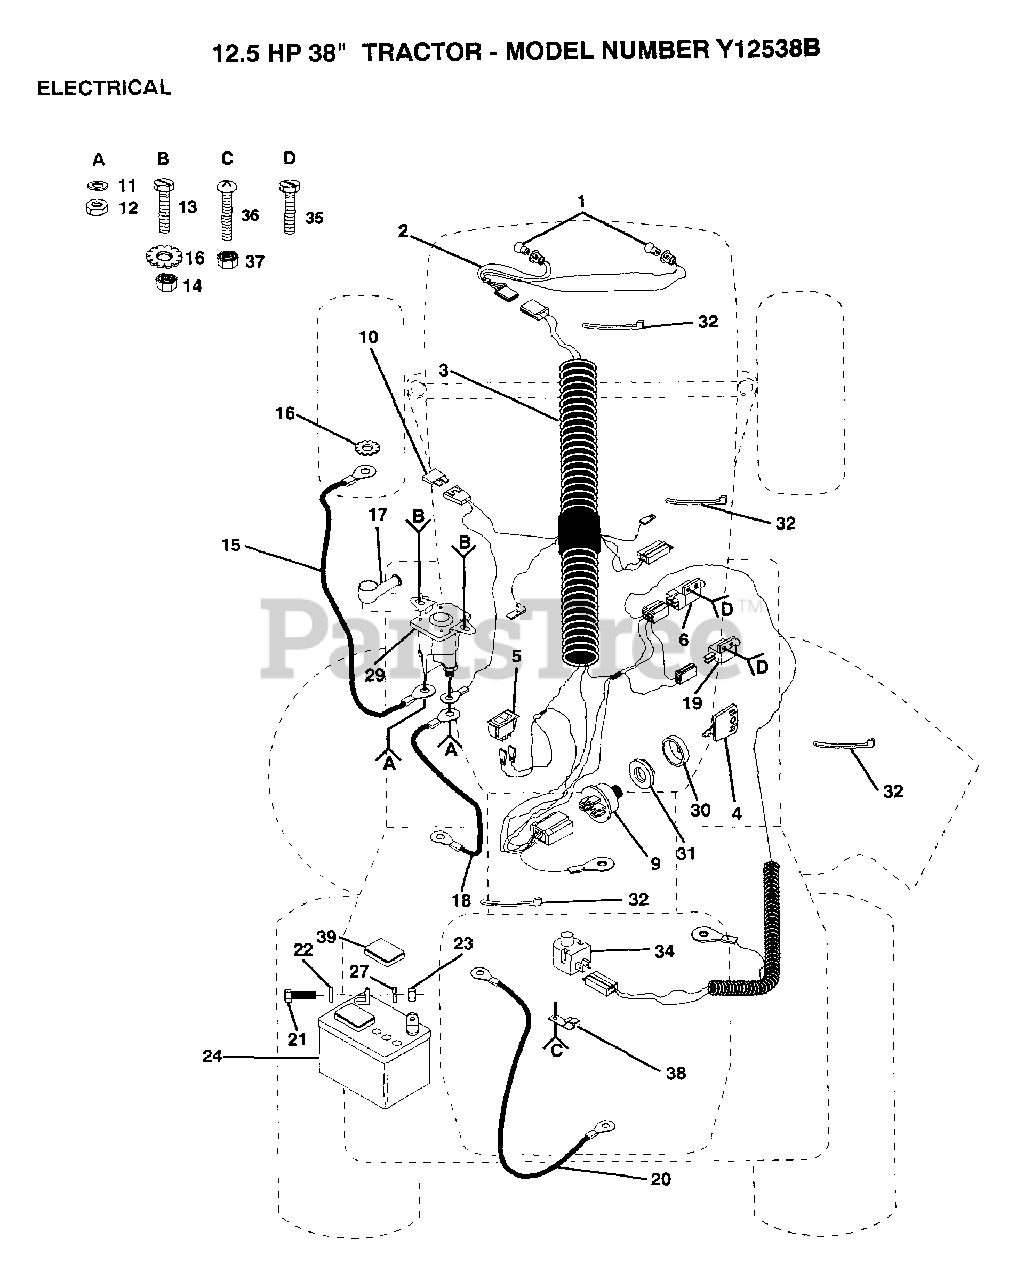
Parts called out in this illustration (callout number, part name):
2	HARNESS T
3	IGN HARNESS
4	KEY
5	SWITCH LT
6	SWITCH INTERLOCKT
10	FUSE HYT
12	NUT
13	BOLT
14	NUT
15	"CABLE T, BATTERY"
19	SWITCH-INTER. GT
20	CABLE T
21	BOLT LT
22	WASHER
27	LOCKWASHER
31	NUT IGNITION
32	WIRE TIE
34	SWITCH SEAT
35	SCREW
37	"NUT,KEPS"
39	"CAP,BATTERY "
